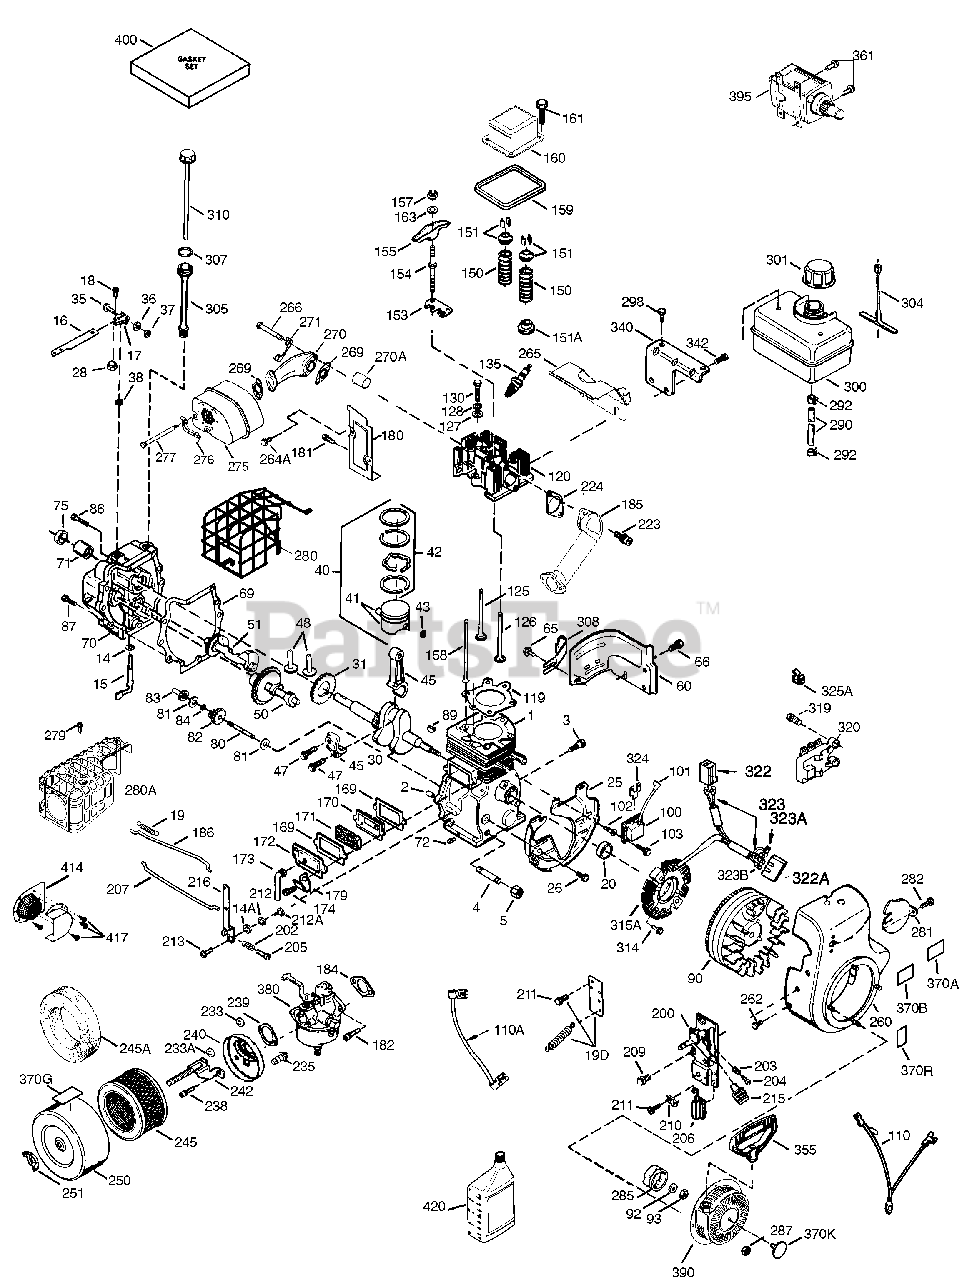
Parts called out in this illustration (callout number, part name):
1	"Cylinder (Incl. 2, 20, 72 & 80)
2	Dowel Pin
14	Flat Washer
15	Governor Rod (Incl. 14 & 38)
16	Governor Lever
17	Governor Lever Clamp
18	Screw, Torx T-15, 8-32 x 3/8"
19	Extension Spring
20	Oil Seal
25	Blower Housing Baffle
26	Screw, 1/4-20 x 5/8"
28	Lock Nut, 10-32
30	Crankshaft
31	Counterbalance Gear
35	Screw, 10-32 x 3/4"
36	Lock Washer #8
37	Lock Nut, 10-32
38	Retaining Ring
40	Piston, Pin & Ring Set (Std) (Incl. 4 1, 42 & 43)
40	Piston, Pin & Ring Set (.010" OS) (In cl. 41, 42 & 43)
40	Piston, Pin & Ring Set (.020" OS) (In cl. 41, 42 & 43)
41	Piston & Pin Assembly (Std) (Incl. 43 )
41	Piston & Pin Ass'y. (.010" OS) (Incl. 43)
41	Piston & Pin Ass'y. (.020" OS) (Incl. 43)
42	Ring Set (Std.) (3-5/16")
42	Ring Set (.010" OS)
42	Ring Set (.020" OS)
43	Piston Pin Retaining Ring
45	Connecting Rod Ass'y (Incl. 47)
47	Connecting Rod Bolt
48	Valve Lifter
50	Camshaft (MCR)
51	Counterbalance Weight
60	Blower Housing Extension
65	Screw, 10-24 x 1/2"
66	Screw, 1/4-20 x 19/32"
69	* Cylinder Cover Gasket
70	Cylinder Cover (Incl. 14, 15, 38, 71 & 75)
71	Crankshaft Bushing
72	Oil Drain Plug (Sq. hd., 1/4-18)
75	Oil Seal
80	Governor Shaft
81	WASHER
82	Governor Gear Assembly
83	Governor Spool
84	Retaining Ring
86	Screw, 1/4-20 x 1-3/16"
87	Screw, 1/4-20 x 1-11/16"
89	Flywheel Key
90	Flywheel (W/Ring Gear)
92	Lock Washer
93	Flywheel Nut
100	Solid State Ignition
101	Spark Plug Cover
102	Solid State Mounting Stud
103	Screw, Torx T-15, 10-24 x 15/16"
110	Ground Wire
119	* Cylinder Head Gasket
120	Cyinder Head
125	Exhaust Valve (Std.)
125	Exhaust Valve (1/32" OS)
126	Intake Valve (Std.)
126	Intake Valve (1/32" OS)
128	Belleville Washer
130	Screw, 5/16-18 x 2-1/2"
135	Resistor Spark Plug (RN4C) also avail able in Packaged Part #740069
150	Valve Spring
151	Valve Spring Keeper
153	Push Rod Guide
154	Rocker Arm Stud
155	Rocker Arm
157	Jam Nut
158	Push Rod
159	* Rocker Arm Cover Gasket
160	Rocker Arm Housing
161	Screw, T-30, 1/4-20 x 1/2"
163	Lock Washer
169	* Valve Cover Gasket
170	Breather Body
171	Breather Element
172	Valve Cover
173	Breather Tube
174	Screw, 10-24 x 1/2"
180	Blower Housing Extension
181	Screw, 10-24 x 9/16"
182	Screw, Torx T-30, 1/4-20 x 27/32"
184	* Carburetor To Intake Pipe Gasket
185	Intake Pipe
186	Governor Link
200	Manual Control Bracket (Incl. 203, 20 4 & 206)
202	Compression Spring
203	Compression Spring
204	Screw, Torx T-10, 5-40 x 7/16"
205	Screw, Torx T-10, 6-32 x 41/64"
206	Terminal
207	Throttle Link
209	Screw, 10-32 x 1/2"
212	Bushing
213	Screw, 10-32 x 5/8"
215	Control Knob
216	R.P.M. Adjusting Lever
223	Screw, Torx T-30, 5/16-18 x 7/8"
224	* Intake Pipe Gasket
233	"O" Ring
233A	"O" Ring
235	Air Cleaner Elbow Fitting
238	Screw, 10-32 x 1/2"
239	* Air Cleaner Gasket
240	Air Cleaner Bracket
242	Air Cleaner Bracket Ass'y
245	Air Filter
245A	Air Filter (Poly)
250	Air Cleaner Cover
251	Wing Nut, 1/4-20
260	Blower Housing
262	Screw, T-40, 5/16-24 x 21/32"
264A	Screw, T-30, 1/4-20 x 1/2"
265	Cylinder Head Cover
266	Screw, 5/16-18 x 1-1/4"
269	* Exhaust Manifold Gasket
270	Exhaust Manifold
270A	Exhaust Port Liner
271	Locking Plate (Manifold)
275	Muffler
276	Locking Plate
277	Screw, 5/16-18 x 4-1/2"
285	Starter Cup
287	Nut & Lock Washer 1/4-28
290	Fuel Line
292	Fuel Line Clamp
298	Screw, 1/4-15 x 3/4"
300	Fuel Tank (Incl. 292 & 301)
301	Fuel Cap
305	Oil Fill Tube
307	"O" Ring
308	Fill Tube Clip
310	Dipstick
314	Screw, 1/4-20 x 3/4"
322	Connector Body
323	Terminal
324	Terminal
325A	Wire Clip
340	Fuel Tank Bracket
341	Fuel Tank Bracket
342	Screw, 5/16-18 x 7/8"
355	Starter Handle
361	Screw, Torx T-30, 1/4-20 x 15/32"
370G	Decal - Important Lubrication - SAE 3
370K	Logo Decal 12 H.P.
371J	Speed Control Decal
380	Carburetor (Incl. 184)
390	Rewind Starter NOTE: This engine cou ld hav e been built with 590704 start er.
395	Electric Starter Motor (12 Volt)
400	Gasket Set (Incl. items marked PK in notes) Incl. part #'s 27272A (1),278 96A (2), 33263 (1), 33515A (1), 3531 7 (1), 35683 (1), 35762 (2), 35952 (1 ), 36333 (1), 36352 (1), 36358 (1), 3 6832 (1), 36930 (1), 36932 (1), 369 42 (1)
420	SAE 30 4-Cycle Engine Oil (Quart)
